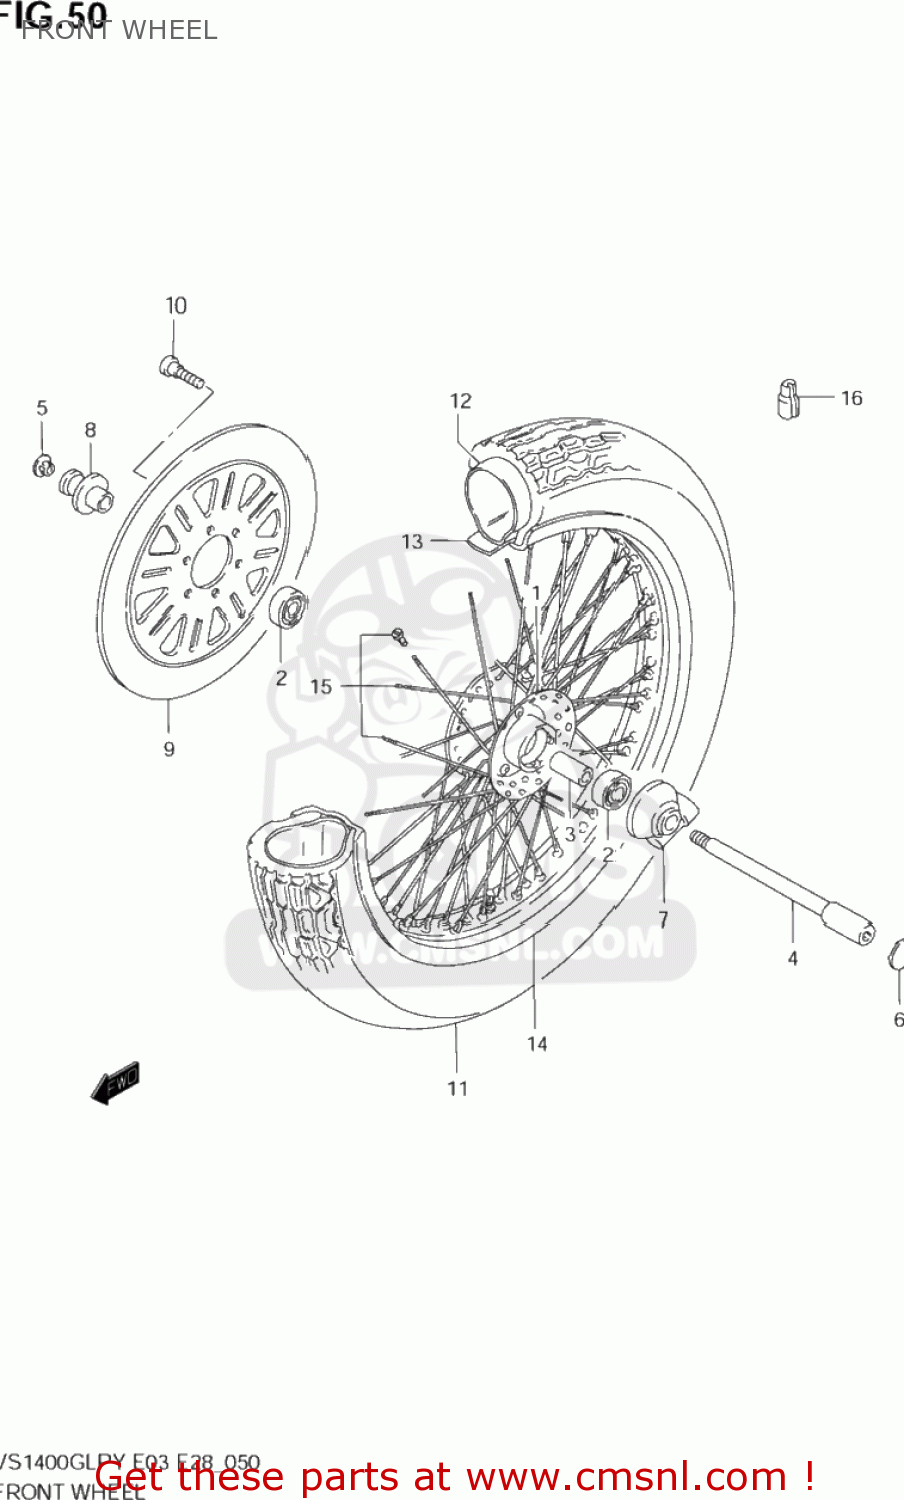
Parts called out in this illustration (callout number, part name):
1	HUB ASSY,FR
2	BEARING
3	SPACER(15.3X21.7X65)
4	AXLE,FR
5	CAP,FR AXLE
6	CAP,FR AXLE
7	BOX ASSY,SPEEDOMETER
8	SPACER,FR AXLE
9	DISC,FR BRAKE
10	BOLT 8X33
11	TIRE,FR(110/90-19 62H)
12	TUBE
13	PROTECTOR, INNER TUBE
14	RIM,FR WHEEL(2.15X19)
15	SPOKE SET,FR WHEEL
16	BALANCER,WHEEL
